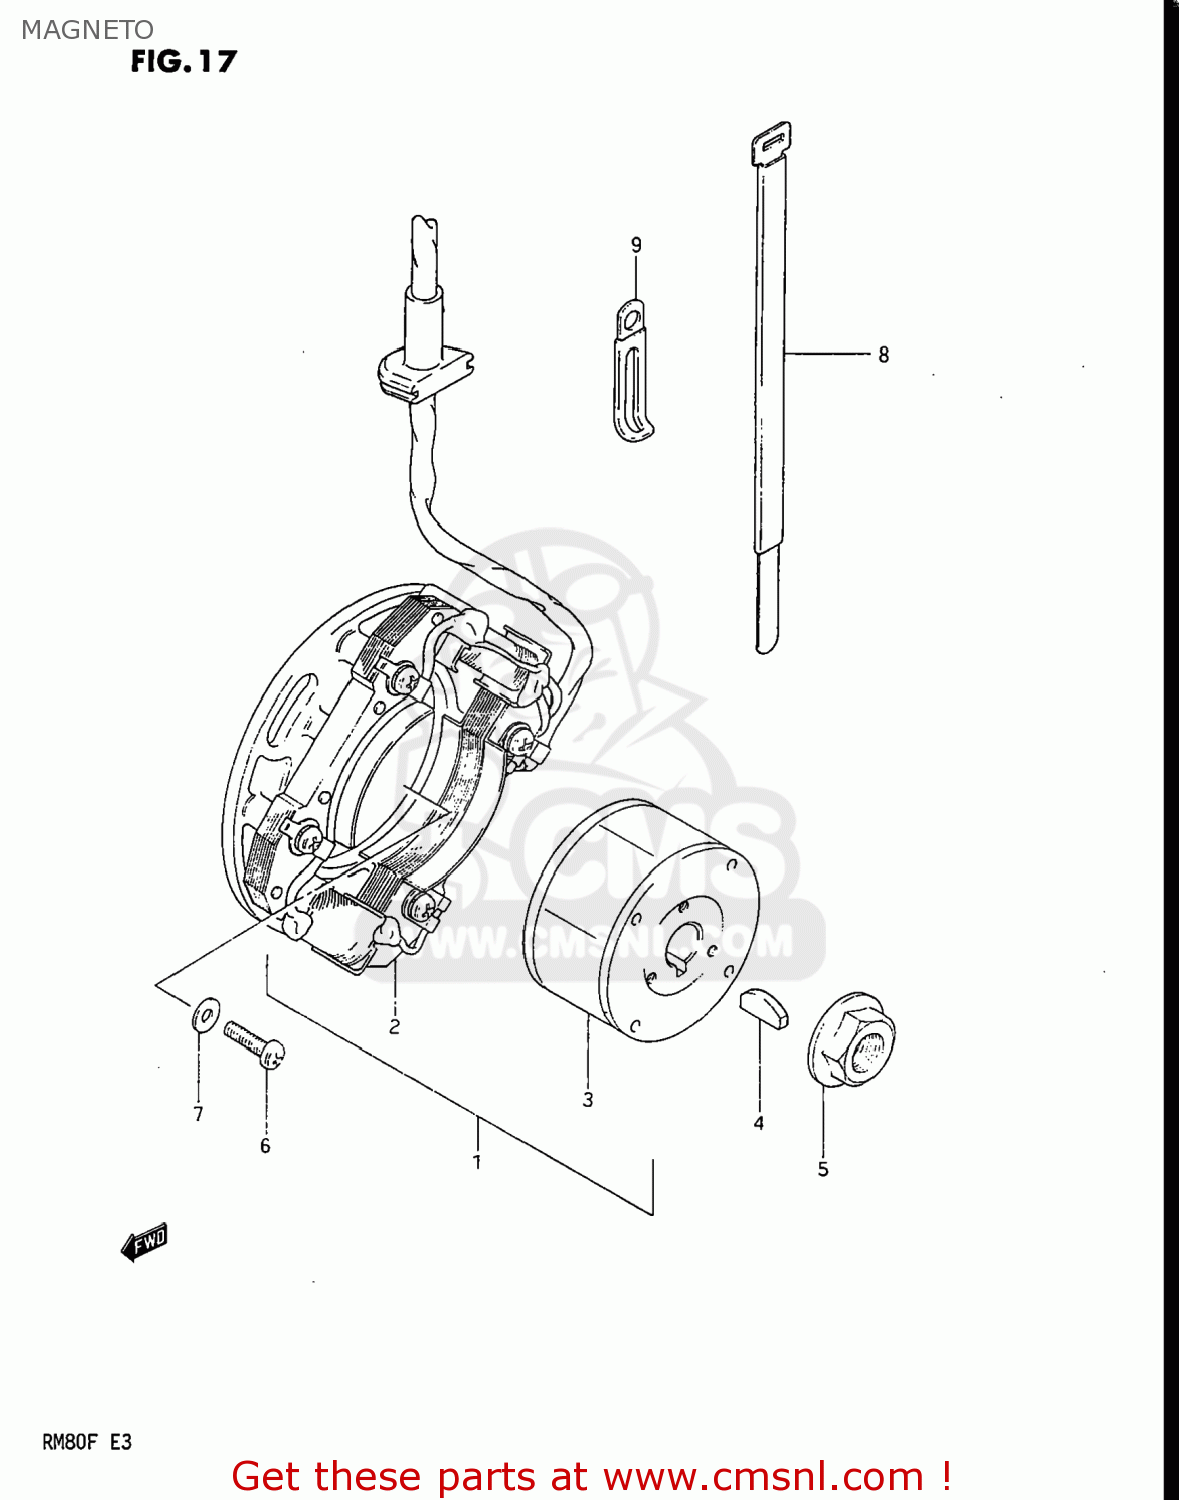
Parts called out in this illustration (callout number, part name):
1	MAGNETO ASSY
2	STARTER ASSY
3	ROTOR ASSEMBLY
4	KEY 4MM
5	NUT
6	SCREW
7	WASHER
8	CLAMP(L:250)
9	CLAMP L:35
